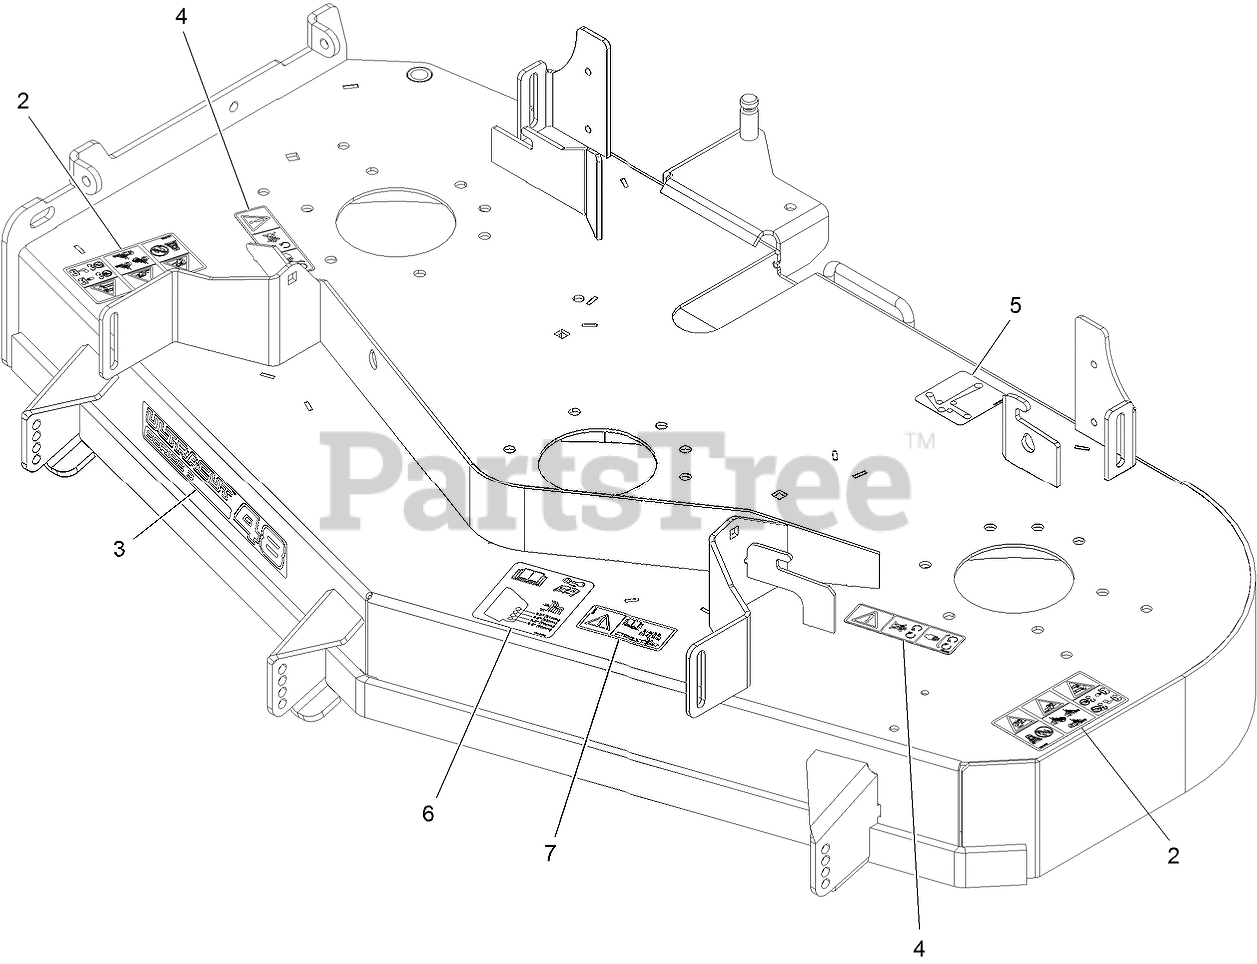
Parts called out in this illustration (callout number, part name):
2	DECAL-DANGER THROWN OBJECTS
3	DECAL-ULTRACUT 48 SERIES
4	DECAL-COVER, MISSING
5	DECAL-ROUTING, BELT
6	DECAL-ROLLER, ANTI-SCALP
7	DECAL-BOLT TORQUE
